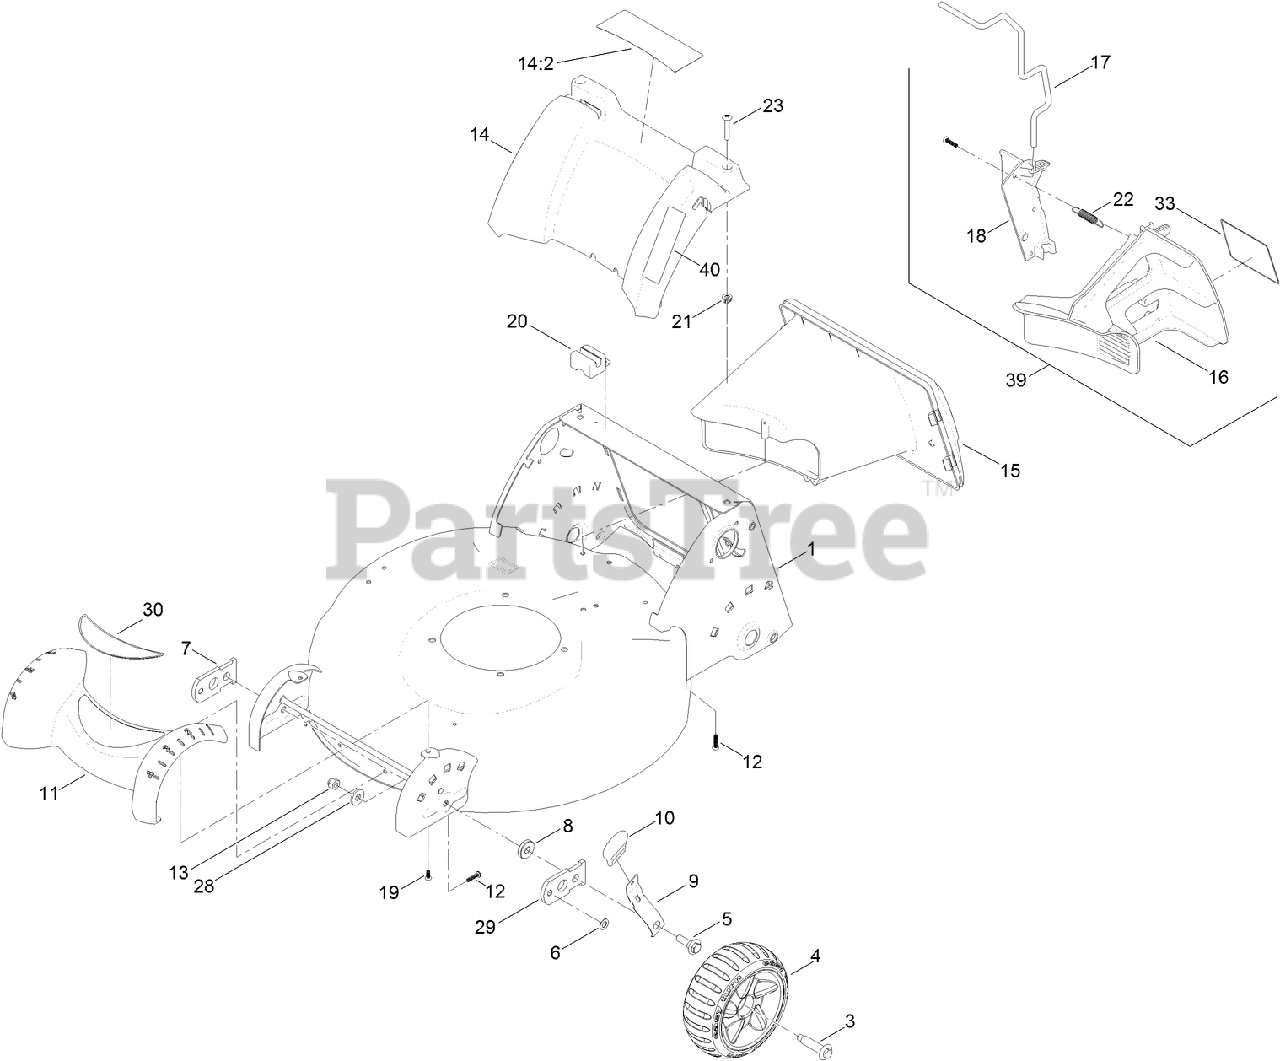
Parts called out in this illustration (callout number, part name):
1	DECK ASM
3	BOLT-SHOULDER
4	7 INCH WHEEL AND TIRE ASM
5	SCREW-SHOULDER, HWH
6	WASHER
7	ARM-PIVOT, RH
8	WASHER
9	ARM-SPRING
10	KNOB-HOC
11	COVER-FRONT
12	SCREW-PLASTITE
13	NUT-LOCK, NI
14	REAR COVER ASM
14:2	DECAL-WARNING
15	TUNNEL
16	PLUG-MULCH, LH
17	LATCH-PLUG, MULCH
18	PLUG-MULCH, RH
19	SCREW-PLASTITE
20	MODULE-SWITCH
21	NUT-CLIP
22	SPRING-EXTENSION
23	SCREW-PTH
28	WASHER-HARDENED
29	ARM-PIVOT, LH
30	DECAL-FRONT (CE)
33	DECAL-PLUG, MULCH
39	MULCH PLUG ASM
40	DECAL-STOW, QUICK
